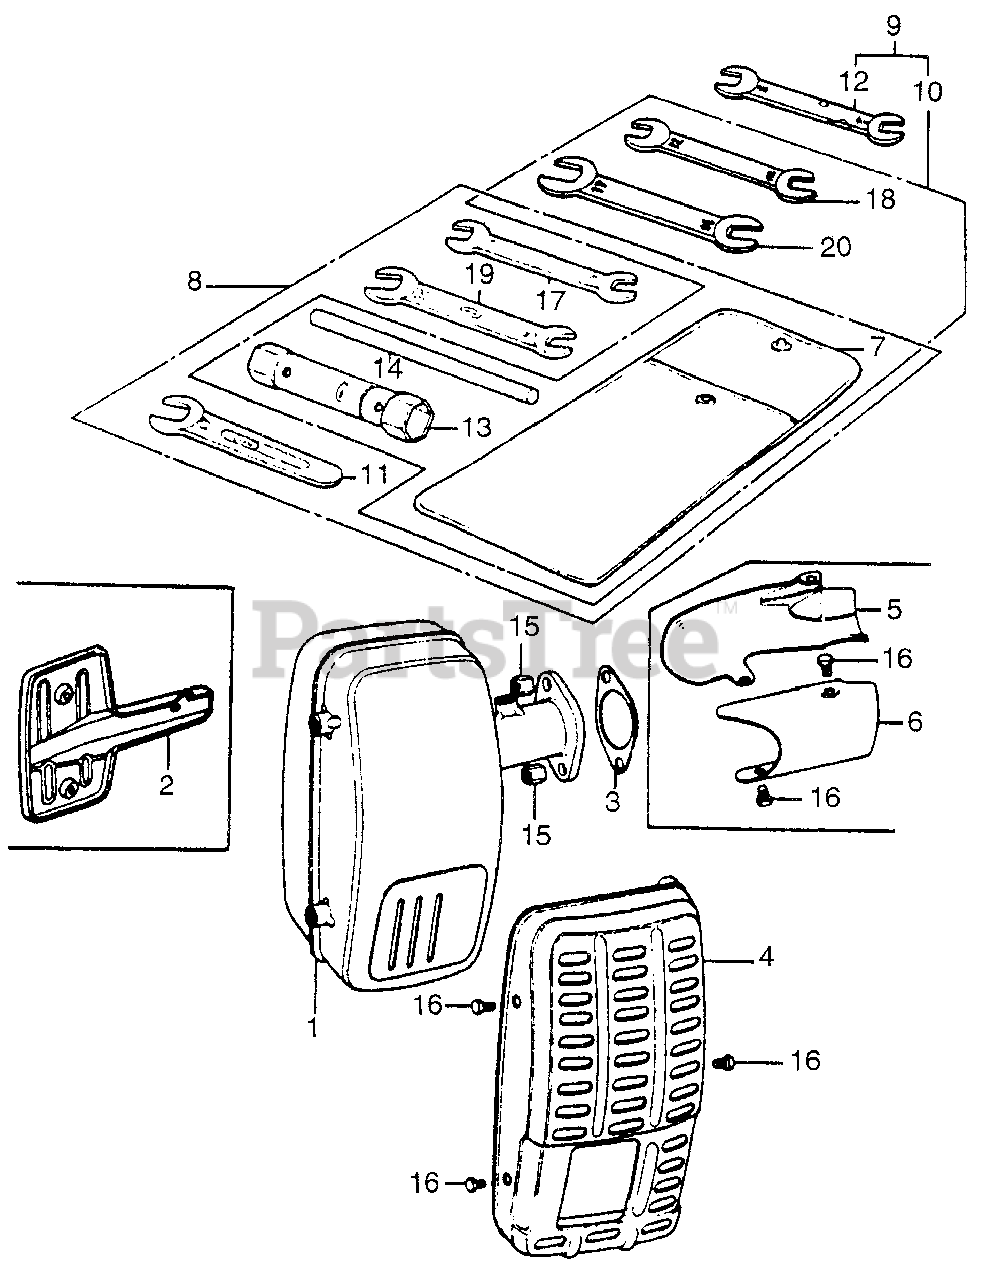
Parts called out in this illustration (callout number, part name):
2	SEPARATOR, MUFFLER
3	GASKET, MUFFLER
4	PROTECTOR, MUFFLER
9	TOOL KIT
10	TOOL KIT
12	WRENCH (8X9)
14	HANDLE, BOX WRENCH
15	NUT, HEX. (6MM)
16	BOLT, HEX. (6X6)
18	WRENCH (10X12) (OPEN END)
20	WRENCH (14X17) (OPEN END)
